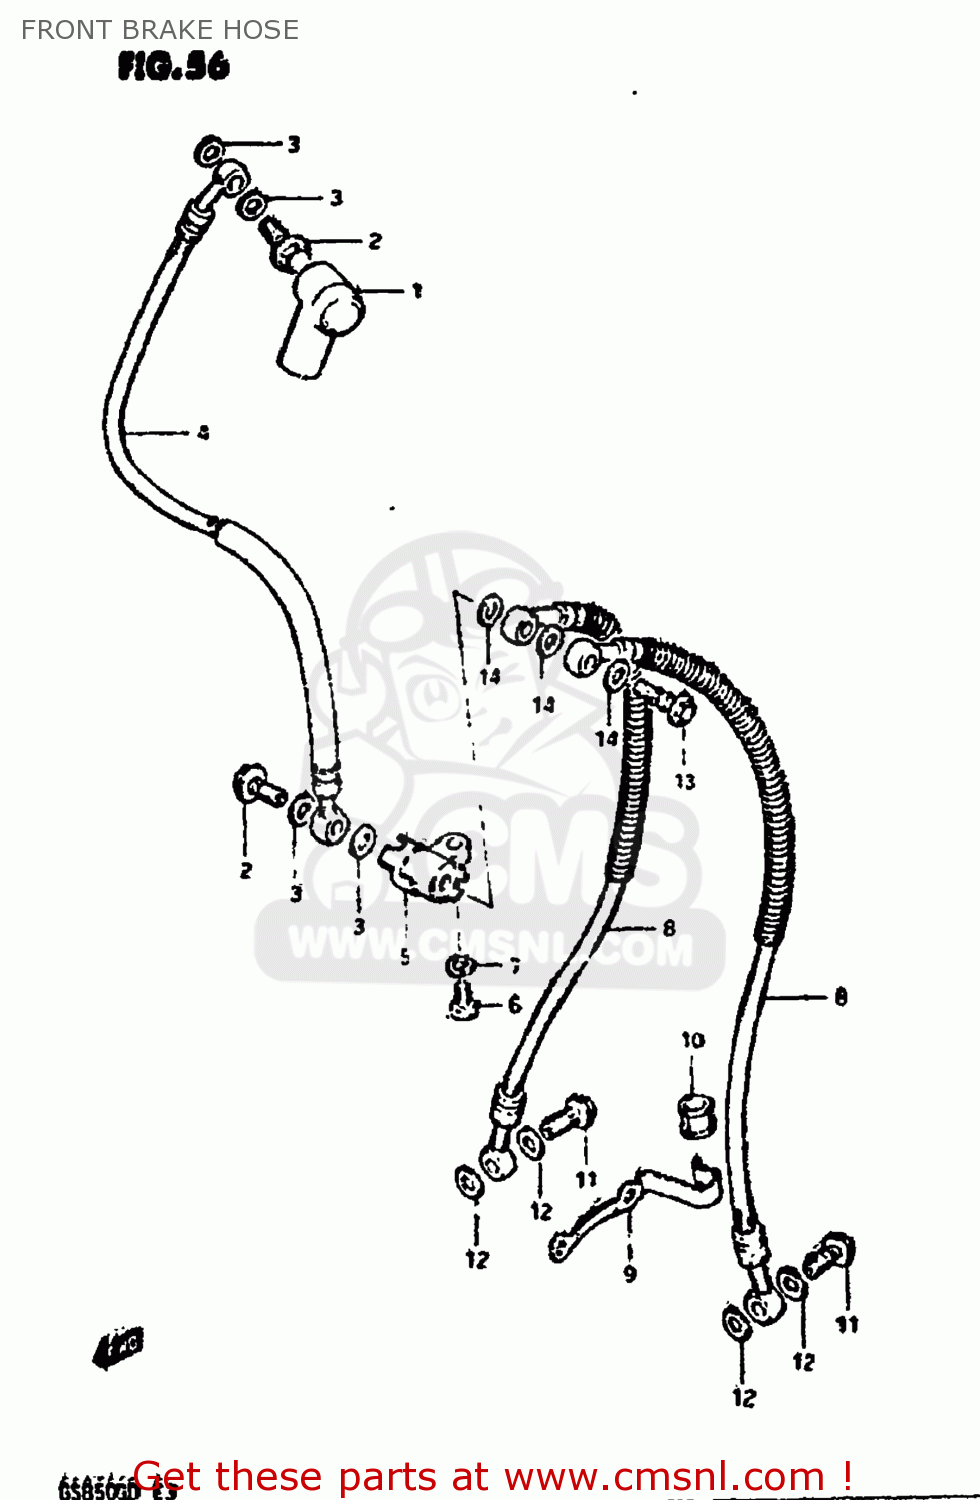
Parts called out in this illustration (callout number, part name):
1	BOOT,MASTER CYLINDER
2	BOLT,UNION
3	WASHER
4	HOSE,BRAKE NO.1
5	JOINT,BRAKE HOSE
6	BOLT
7	LOCK WASHER
8	HOSE,FRONT BRAKE
9	GUIDE,BRAKE HOSE NO.2
10	BUSH,BRAKE HOSE GUIDE,NO.2
11	BOLT,UNION
12	WASHER
13	BOLT,UNION
14	WASHER
